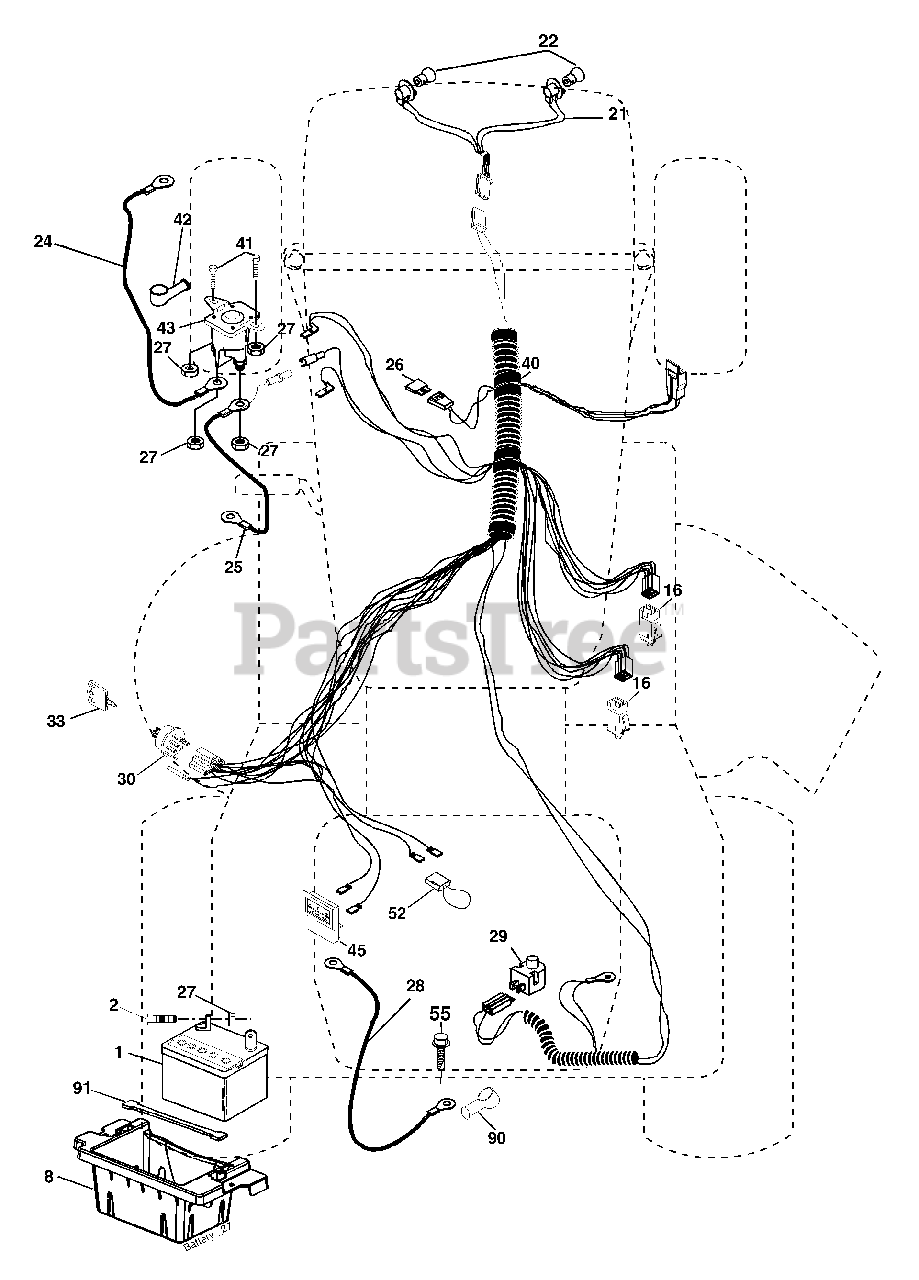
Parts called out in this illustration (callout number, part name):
1	Battery
2	Bolt Hex Hd 1/4-20 unc x 3/4
8	Box Battery
16	Switch Interlock
21	Harness Socket Light
22	Bulb, Light # 1156
24	Cable Battery
25	Cable Battery 6 Ga. Red w/16 wire
26	Fuse
27	Nut Keps Hex 1/4-20 unc
28	Cable Ground 21" Blk 6 Ga.
29	Switch Plunger Nc Gray
30	Switch Ign
33	Key Ign Molded Generic
40	Harness Ign
41	Bolt Fin Hex 1/4-20 unc x 1/2
42	Cover Terminal Red
43	Solenoid
45	Ammeter Rectangular
52	Protection Loop
55	Screw Thdrol 5/16-18 x 1/2
90	Cover Terminal
91	Strap Battery Mount Front
